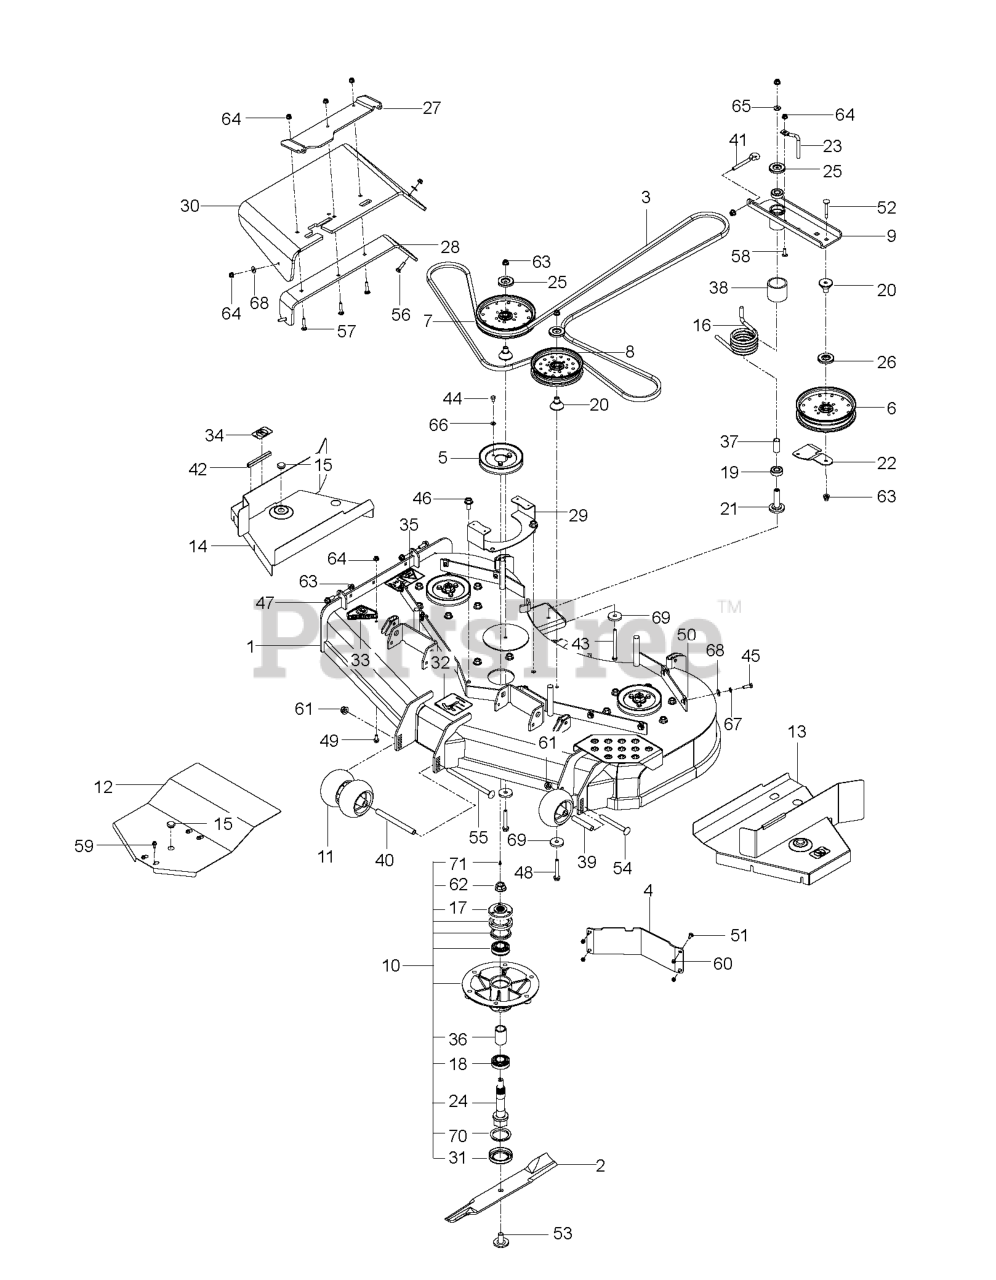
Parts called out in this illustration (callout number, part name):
1	DECK.SVC W/DECALS.60.ORANGE
2	BLADE - HEAVY DUTY 21"
3	RP.BELT, "5V", 176"
4	BAFFLE, DIVERTER 54"/60" LH
5	PULLEY - 6.57
6	PULLEY - IDLER 7"
7	PULLEY - 7" NARROW
8	PULLEY IDLER, 6" NARROW
9	IDLER.ARM.BLACK
10	SPINDLE ASM. 10"
11	ROLLER, GAUGE .635 BORN
12	GUARD.CENTER.PZ.G60.BL
13	WELDMENT.LEFT.PZ.G60.BLACK
14	WELDMENT.RIGHT.PZ.G60.BLACK
15	PLUG, BUTTON HOLE
16	SPRING, TORSION, IDLER
17	HUB - PULLEY
18	BEARING - 206KRR8
19	BEARING, BALL
20	BEARING, IDLER ARM
21	BEARING, IDLER PIVOT
22	BELT.GUIDE.BLACK
23	BELT KEEPER
24	SHAFT - SPINDLE
25	DUST SHIELD
26	SHIELD, DUST
27	BRKT - CHUTE MTG BLACK
28	BRKT, CHUTE SUPPORT BLACK
29	BRACKET GUARD.PZG.BLK
30	CHUTE, DISCHARGE 48-52
31	CUP - DEBRIS
32	DECAL, BELT ROUTING
33	DECAL, CPSC
34	DECAL, NO STEP
35	DECAL, EURO SEVERING
36	SPACER - BEARING
37	SPACER, IDLER BEARINGS
38	SPACER, IDLER PIVOT
39	TUBE, ROLLER AXLE
40	TUBE, ROLLER AXLE LONG
41	EYE BOLT, 3/8 X 4"
42	RP.FLEX TRIM, BLK-LENGTH 1 FT
43	HCS 3/8-16 X 4-1/2 GR 8 ZD
44	HCS 5/16-18 X 1/2 GR 5 ZD
45	HCS 1/4C X 1
46	HHFS 1/2-13 X 1 GR5 ZD
47	HHFS 3/8-16 X 1 GRD 5 ZD
48	HHFS 5/16-18 X 3 3/4
49	HHFS 5/16-18 X 3/4
50	U-CLIP 5/16-18 NUT RETAINER
51	1/4-20X3/4 CARR BLT
52	CARRIAGE BOLT 3/8-16 X
53	BLADE BOLT/WASHER
54	RHSNB 1/2-13 X 4.75 GR5 ZD
55	RHSNB 1/2-13 X 8 GR5 ZD
56	BOLT, CARRIAGE 5/16X1-1/4
57	RHSNB 5/16-18 X 1-1/2 GR 5 ZD
58	RHSNB 5/16C X 1
59	SCREW- 1/4-20 X 5/8
60	NUT.1/4-20.HEX.NYLOC.ZD
61	NUT, 1/2-13 HEX FLG NYLOC ZD
62	NUT FLANGE 3/4-16
63	NUT 3/8-16 HEX FLG NYLOC ZD
64	5/16-18 NYLOC FLANGE NUT
65	WASHER, 3/8 THICK
66	WASH 5/16 DISC SPRING ZD
67	WASHER.LOCK.HVY.HLCL.SPR.5/16
68	WASHER 5/16 FLAT
69	SPINDLE WASHER
70	V-RING, 55MM
71	ZERK
